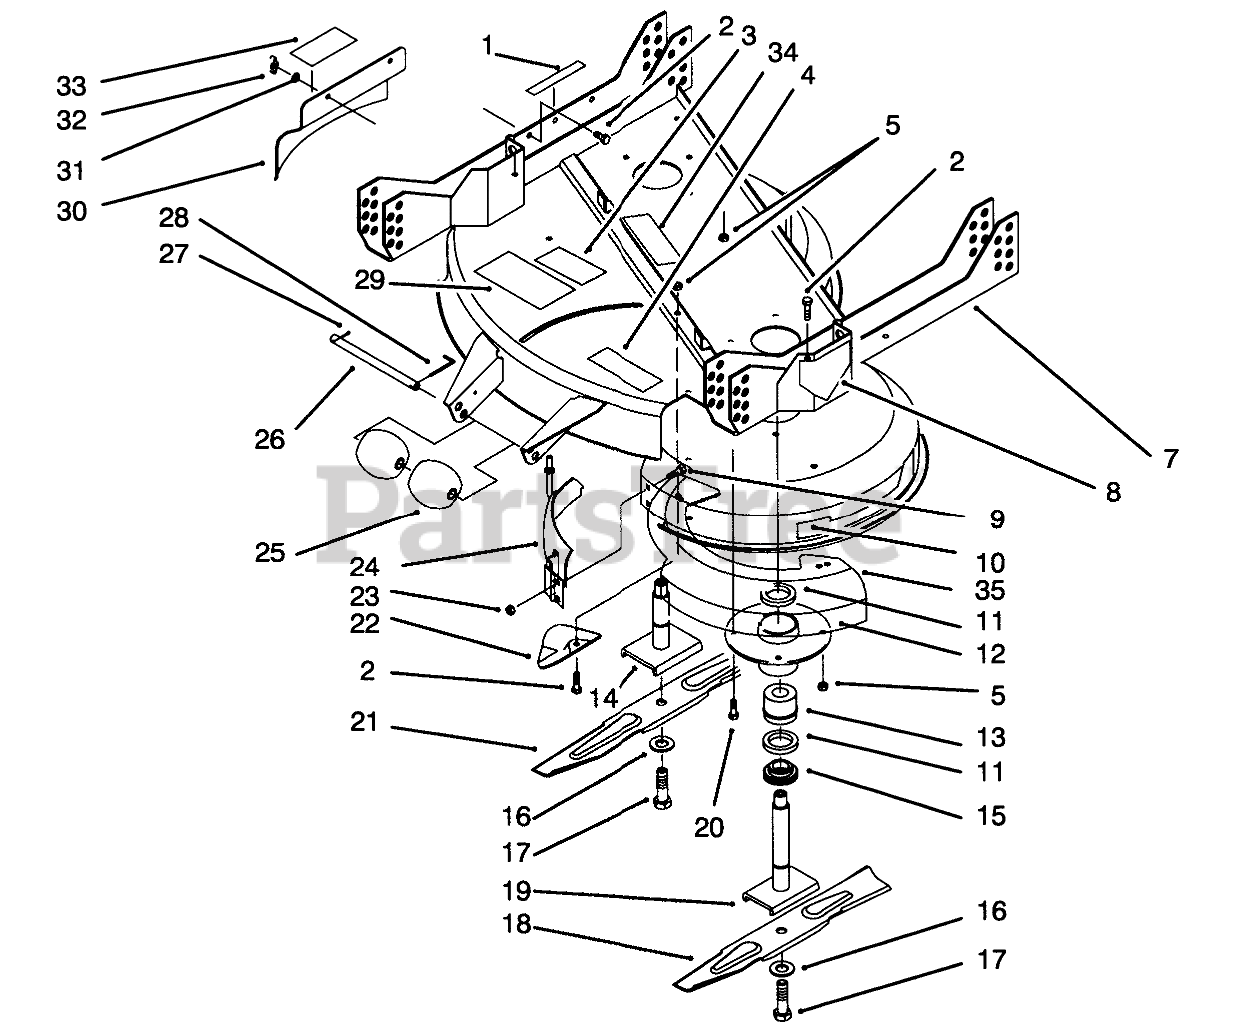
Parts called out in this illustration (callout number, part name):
1	DECAL-DANGER, DEFLECTOR
2	SCREW-HH
3	DECAL-TORQUE
4	DECAL - DISCHARGE DOOR
5	NUT-LOCK, NI
7	Deck Support (Incl. Ref. #3, 4, 6, 8, & 29)
8	DECAL-DANGER
9	SCREW-CARRIAGE
10	DECAL - 37"
11	SEAL-OIL
12	SPINDLE HOUSING
13	BEARING ASM
14	SHAFT-SPINDLE
15	SPACER
16	WASHER-LOCK
17	SCREW-BLADE
18	Blade
19	SHAFT-SPINDLE
20	SCREW-HH
21	Blade
22	PLATE-KICKER
23	NUT-KEPS
24	Cover-Front
25	ROLLER
26	SHAFT-ROLLER
27	PIN-COTTER
28	PIN-SPECIAL
29	DECAL-DANGER, THROWN OBJECT
30	Cover-Discharge
31	WASHER-LOCK
32	NUT-WING
33	DECAL - DANGER
34	DECAL-DANGER
35	Insert-Deck
